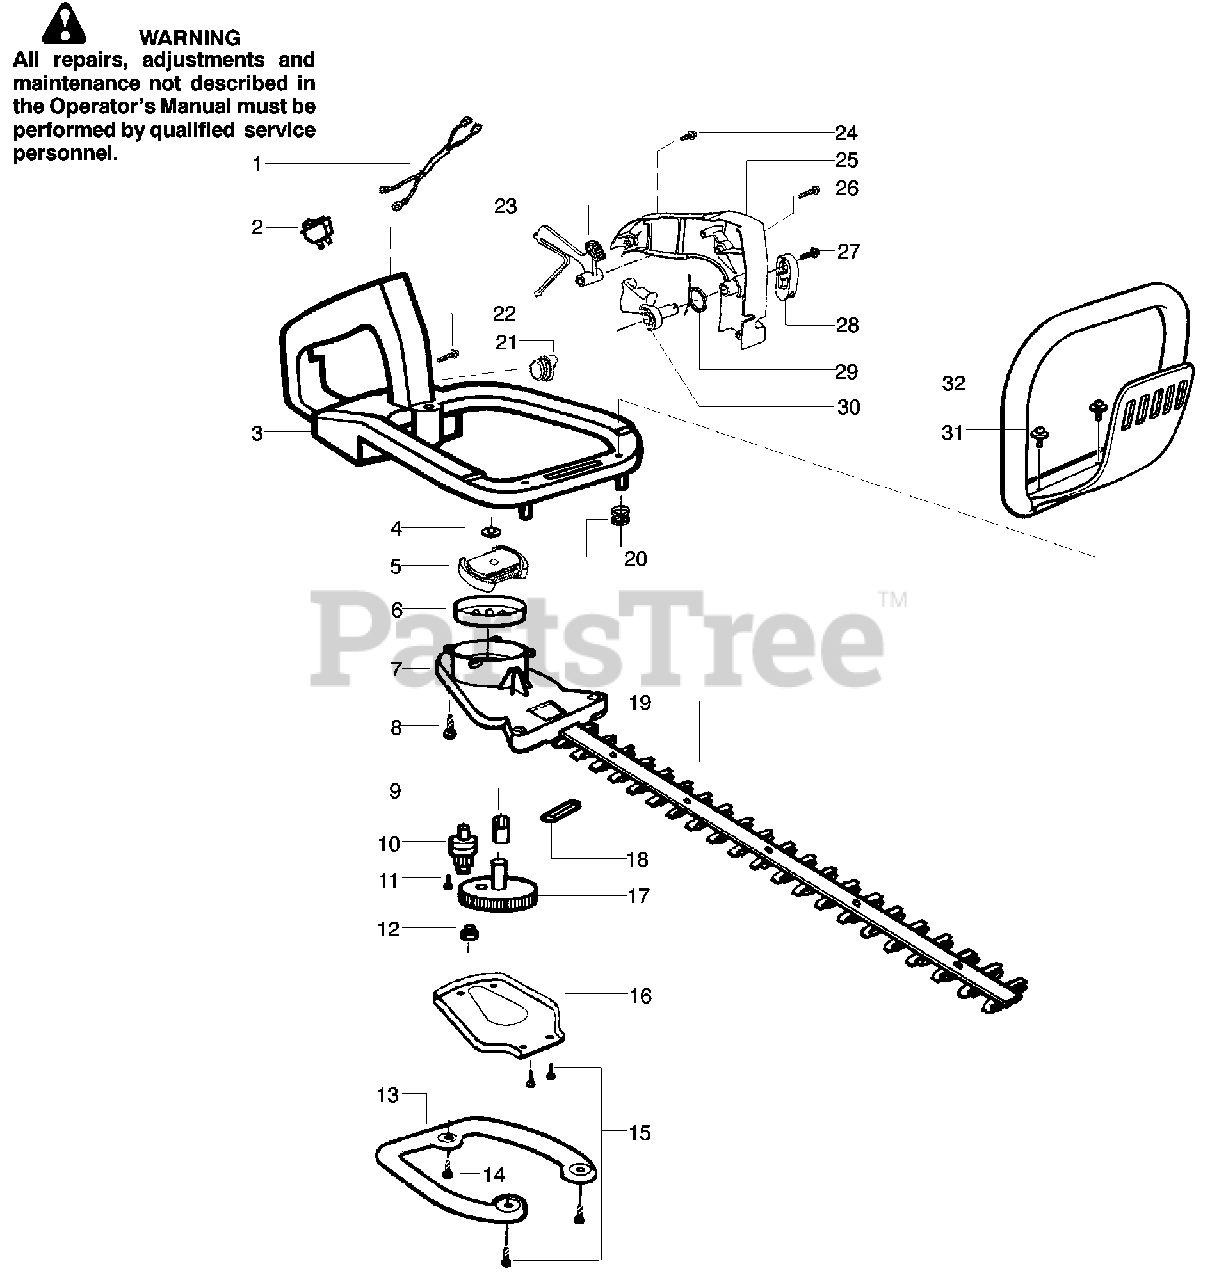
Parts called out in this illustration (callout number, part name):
1	Assy-Leadwire/Switch
2	Switch-Ignition
3	Assy-Rear Handle & Tank
4	Washer-Clutch
5	Kit-Clutch Assy.
6	Assy-Drum
7	Assy-Gear Box
9	Bearing-Gear
10	Assy-Pinion
11	Screw
12	Bushing-Blade
13	Plate-Isolator
16	Cover-Gear Box Plate
17	Kit-Drive Gear Ass'y.
18	Seal-Blade (Felt)
19	Assy-Blade Blade 19"
19	Assy-Blade Blade 22"
21	Assy-Fuel Cap
23	Lockout-Throttle
25	Cover-Handle
28	Lever-Trigger
29	Spring-Trigger
32	Handle-Front
